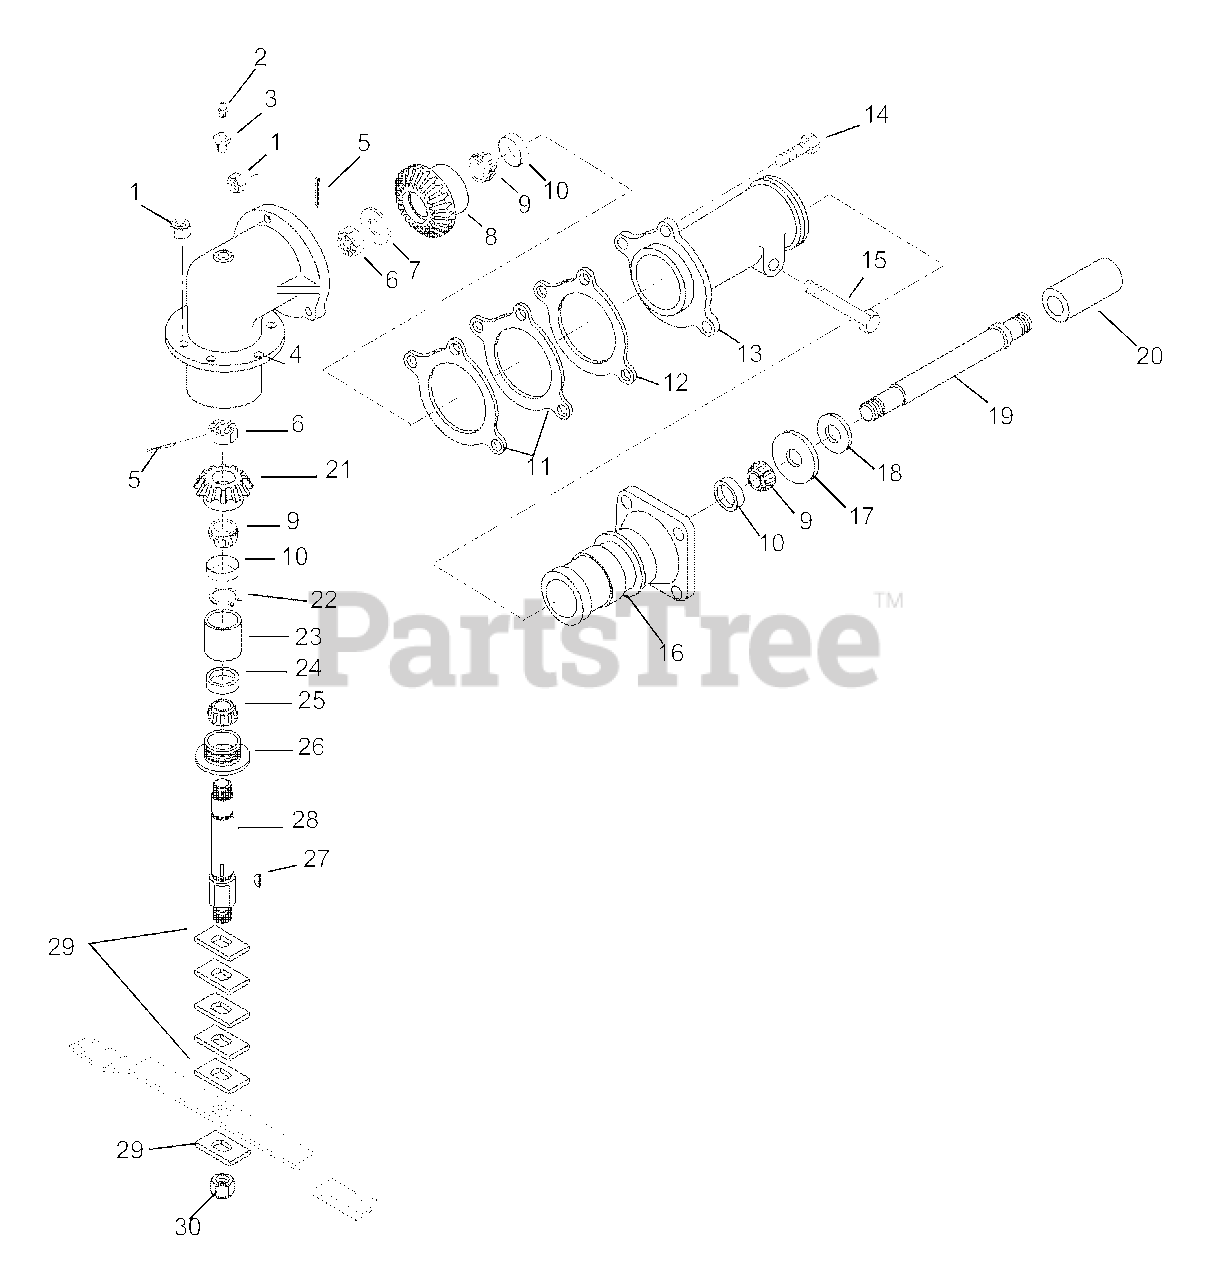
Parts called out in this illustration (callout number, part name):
1	Nut-Locking-Nylon .50-13
2	Fitting-Lube .125
3	Bushing-Reducing Pipe .5
4	Housing-Gear
5	Pin-Cotter .094 x 1.25
6	Nut-Hex-Slotted .625-18
7	Washer-Flat-Steel .656 x 1.31 x .095
8	Gear-Bevel
9	Cone-Roller Bearing
10	Cup-Roller Bearing
11	Shim .020
12	Shim .005
13	Casting-Swivel
14	Bolt-Hex .50-13 x 1.75
15	Bolt-Hex .50-13 x 3.25 Grade 5
16	Housing-Shaft
17	Washer-Flat-Steel 1.006 x 2.247 x .060
18	Washer-Hardened-Thrust 1.00 x 1.55 x .03
19	Shaft-Drive
20	Coupling
21	Pinion-Bevel
22	Ring-Retaining-Internal 2.210 x .062
23	Bushing 1.75 x 1.94 x 1.94
24	Bearing-Cup 1.980 x .420
25	Bearing-Cone 29mm x .58
26	Seal
27	Key-Woodruff .13 x .38
28	Shaft-Rotor
29	Spacer-Cutting Height .25
30	Nut-Locking .875-9
